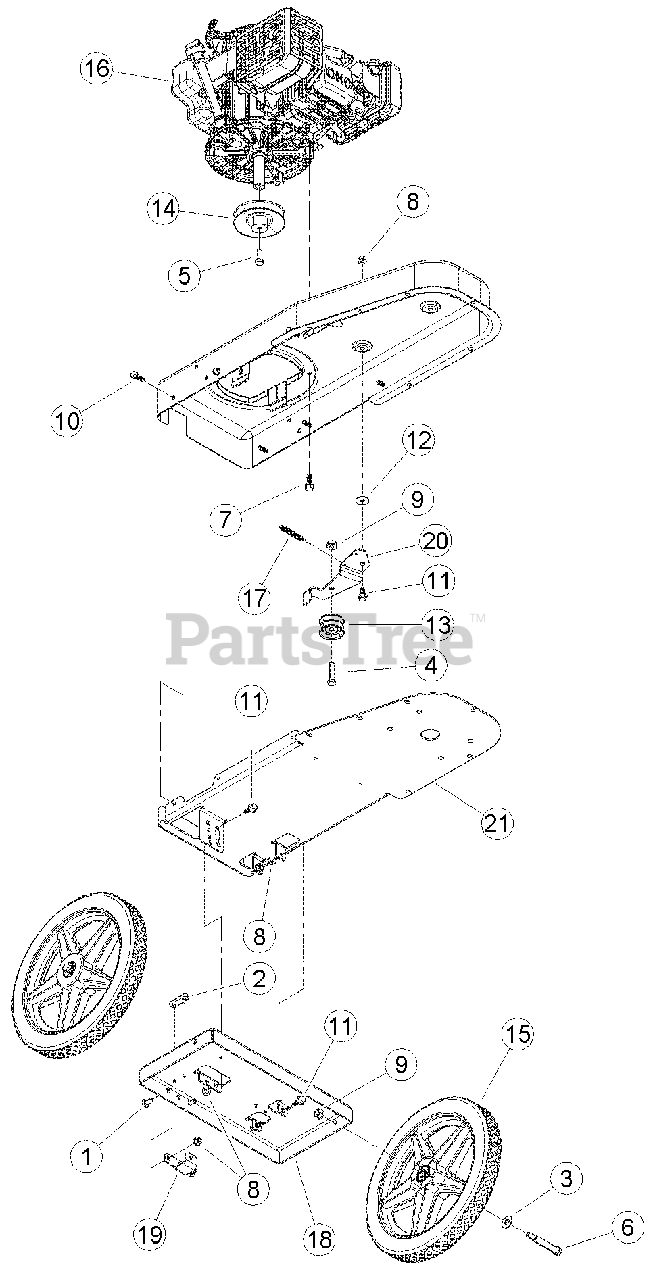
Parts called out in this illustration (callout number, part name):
1	BOLT, 5/16 X 3/4 CRG SHORT NECK
2	WEAR PAD, MEDIUM SPHD FRONT
3	WASHER, 1/2 SAE FLAT
4	BOLT, 3/8 X 1 HEX GR8 NF ZP
5	BOLT, 3/8-16 X 3-1/4 FLANGE SHOULDER ZP
6	BOLT, 3/8 X 1-3/4 HEX GR5 ZP
7	SCREW, 3/8-16 X 1 HEX THREAD ROLLING TRI-LOBE ZP
8	NUT, 5/16-18 NYLOCK FLANGE
9	NUT, 3/8-16 NYLOCK FLANGE
10	SCREW, 5/16-18 X 1 INZP THREAD ROLLING
11	BOLT, 5/16-18 X 3/4 FLANGE SHOULDER .150 ZP
12	WASHER, 1.062 OD X .329 ID X .062 FLAT ZP
13	IDLER, 1-7/8 DOUBLE FLANGE
14	PULLEY, 4.0 X 7/8 BORE B GROOVE CAPPED
15	WHEEL, 14 X 1.75 TRIMMER
16	ENGINE, EA190V SUBARU (FOR SERVICE CONSULT ENGINE OWNER'S MANUAL OR YOUR NEAREST AUTHORIZED SUBARU INDUSTRIAL ENGINE DEALER.)
17	SPRING, IDLER EXTENSION
18	PLATE, TRIMMER TILT SUPPORT
19	BRACKET, HEIGHT ADJUSTMENT
20	BRACKET, IDLER ENGAGEMENT
21	PLATE, TRIMMER TILT BASE
